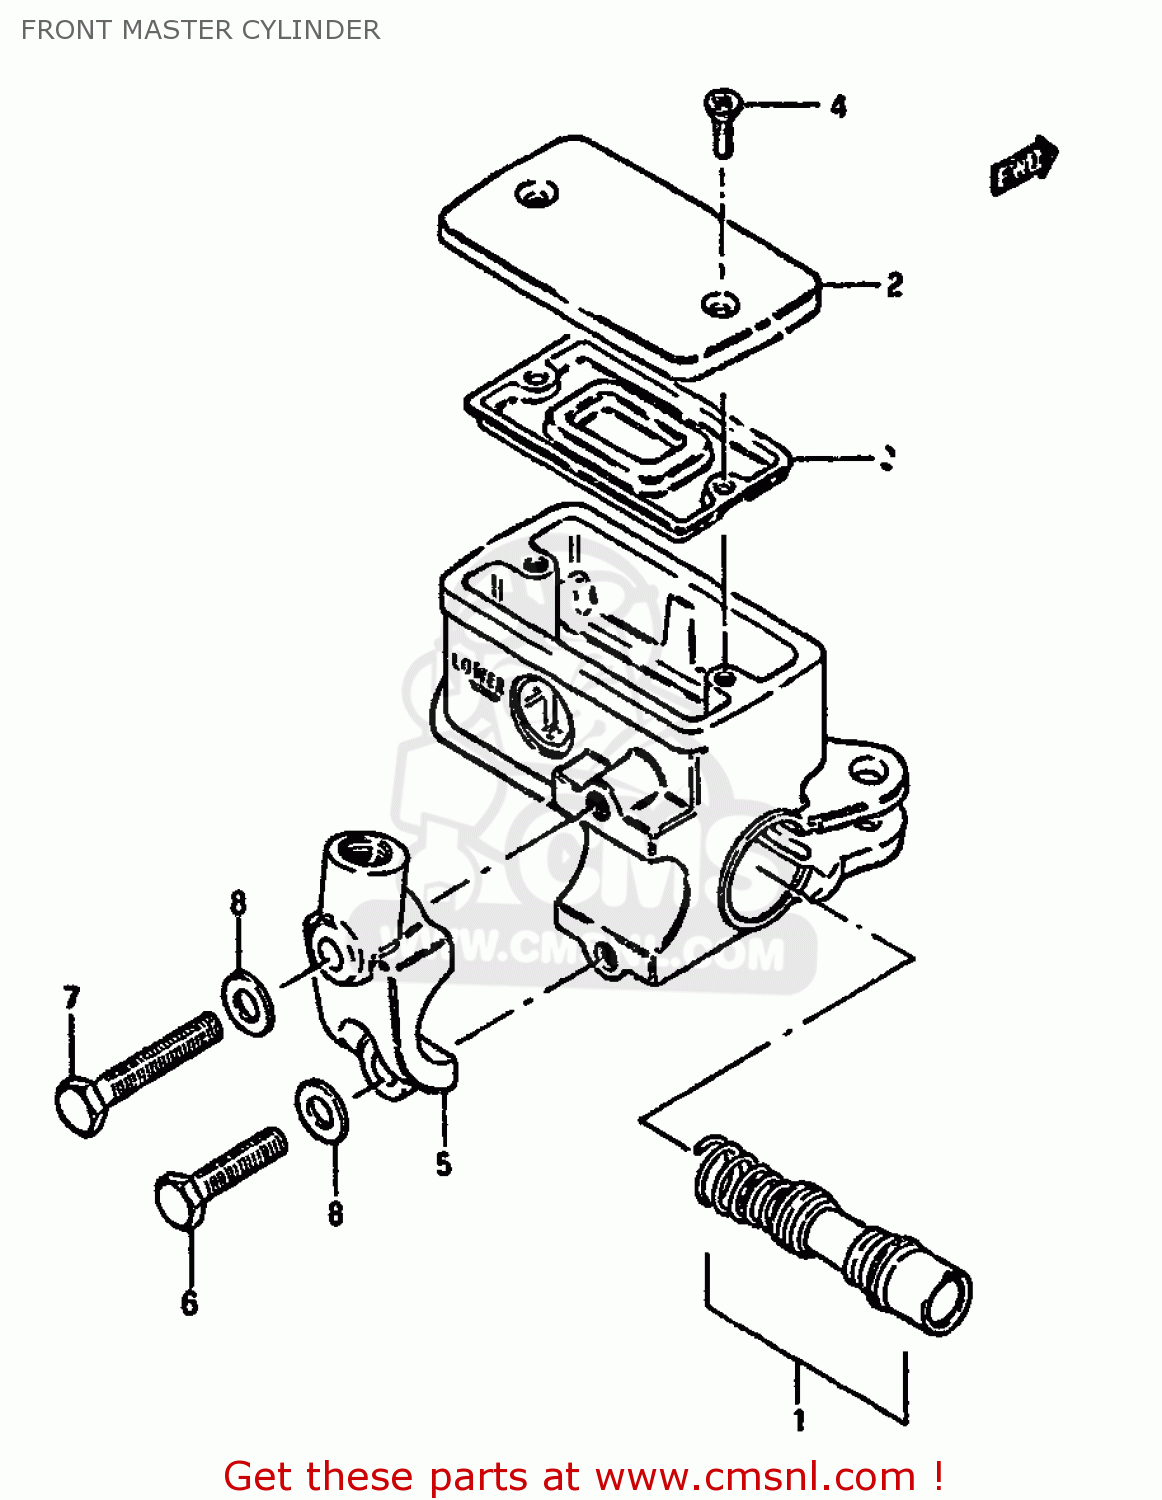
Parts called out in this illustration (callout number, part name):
1	PISTON & CUP SET
2	CAP
3	4
4	SCREW
5	HOLDER
6	BOLT
7	BOLT
8	WASHER
